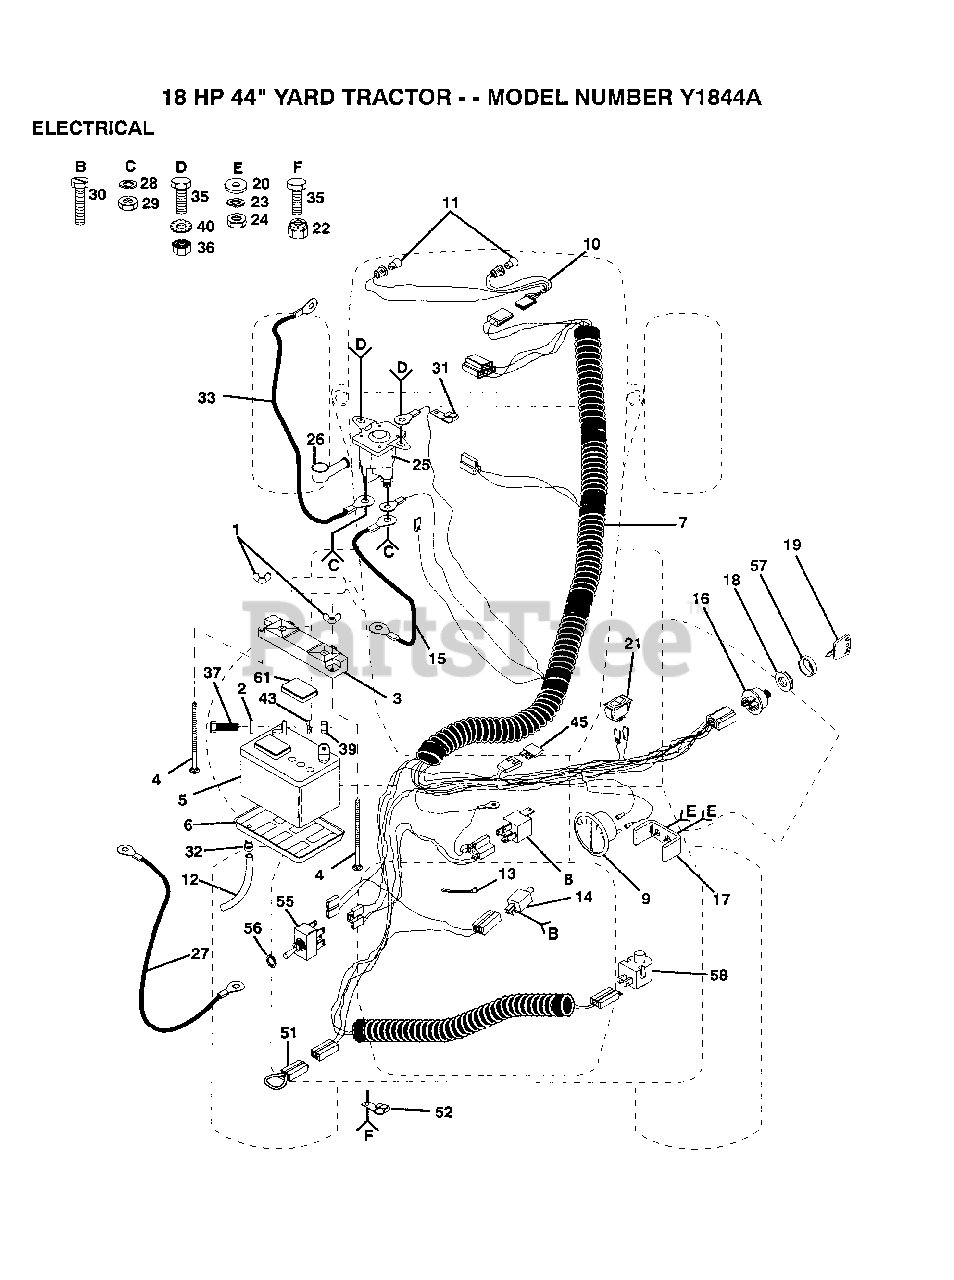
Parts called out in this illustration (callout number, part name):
2	WASHER
4	BOLT
6	"TRAY T, BATTERY"
8	RELAY ASSY T
9	AMMETER T
13	WIRE TIE
14	SWITCH-INTER. GT
15	CABLE-BATTERY T
16	JOINT CRT
18	NUT IGNITION
19	KEY
20	WASHER
21	SWITCH LT
27	CABLE T
29	NUT
30	SCREW
31	CLIP T
32	HOSE CLAMP T
33	"CABLE T, BATTERY"
35	BOLT
36	NUT
37	BOLT LT
43	LOCKWASHER
45	FUSE HYT
52	CLIPT
56	HEX NUT T
58	SWITCH SEAT
61	"CAP,BATTERY "
